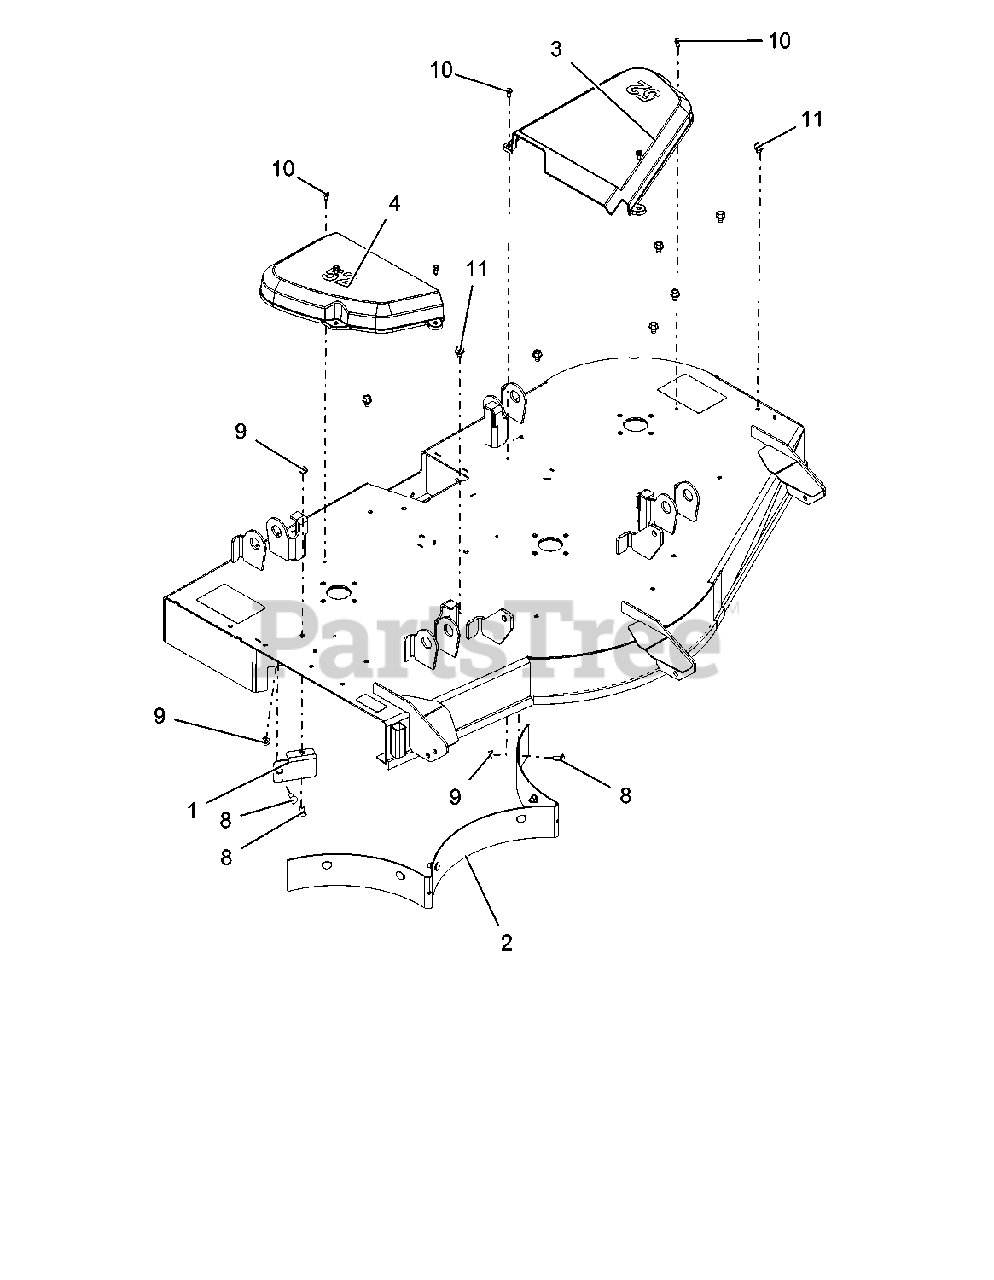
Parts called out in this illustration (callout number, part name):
1	STRIP, DEFLECTOR 52"
2	BAFFLE, REAR - REMOVABLE 52"
3	COVER, BELT 52" LH
4	COVER, BELT 52" RH
8	BLT-RDHDSQNK .31-18X.75 G5 YWZC
9	NUT, LK-TOP-FLG .312-18 YWZC
10	SCR-TAP .25-20X.50 HWH TR YWZ
11	SCR-TAP .38-16X.50 HWH TR YWZ
